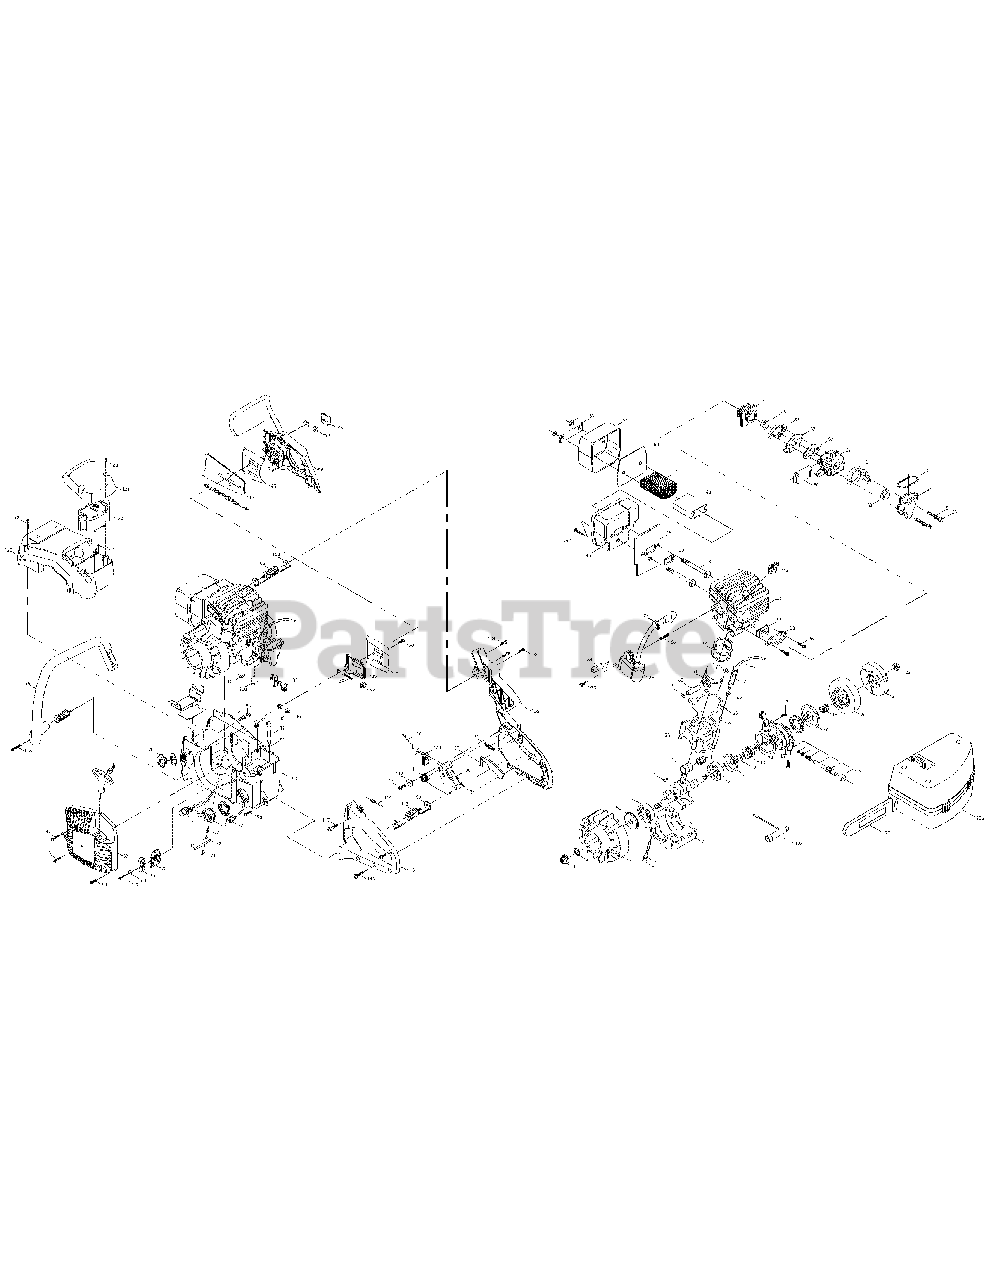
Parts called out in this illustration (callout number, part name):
1	NUT
3	FLYWHEEL
5	WASHER
6	SEAL
7	BEARING
8	CRANKCASE LOWER
10	C'SHAFT/C'ROD ASS'Y
11	BEARING
12	WASHER
13	GEAR, WORM
14	WASHER
16	PUMP ASS'Y
17	SCREW
18	WASHER
19	BEARING
20	FRUM SPRKT ASS'Y
21	CLUTCH ASS'Y
22	NUT
23	CRANKCASE UPPER
24	FITTING, PULSE LINE
25	GASKET
26	CLAMP, WIRE HOSE
27	CONDUIT, FLEX
30	PIN
32	RING, PISTON
35	IGNITION ASS'Y
36	STUD
37	GROMMET
39	FLANGE
40	EYELET
41	CYLINDER
42	SPARK PLUG
44	WASHER
45	BAFFLER
46	MUFFLER BODY ASS'Y
50	BAFFLER
51	COVER, MUFFLER
52	LOCKPLATE
53	NUT
54	BOOT, CARBURETOR
56	FLANGE
57	PLATE
58	GASKET
59	CARBURETOR
60	BOOT 1
63	EYELET
64	BOOT
67	STARTER ASS'Y
68	WASHER
70	SCREEN
74	PRIMER, REMOTE
76	CAP, FUEL
77	FILTER, FUEL
78	SCREW
79	CAP, OIL
80	FUEL/OIL TANK ASS'Y
81	VALVE DUCKBILL
82	FILTER
84	PLUG
90	PLATE, BAR
91	PLATE, FLANGE
93	20" CHAIN
96	CHAIN BRAKE ASS'Y
97	NUT
98	PLATE
99	CKOKE ASS'Y
100	ROD, CHOKE
102	ISOLATOR ASS'Y
103	CABLE ASS'Y
104	SCREW
105	FRAME, REAR
106	PLUG
107	RELEASE, TRIGGER
108	TRIGGER
109	GROMMET
111	SPRING
112	WASHER
113	ISOLATOR ASS'Y
114	WIRE ASS'Y
115	COVER ASS'Y, HANDLE
117	SCREW
119	HANDLE ASS'Y
120	COVER ASS'Y
123	AIR CLEANER ASS'Y
124	COVER
125	WRENCH
126	CARRY CASE
127	SCABBARD
